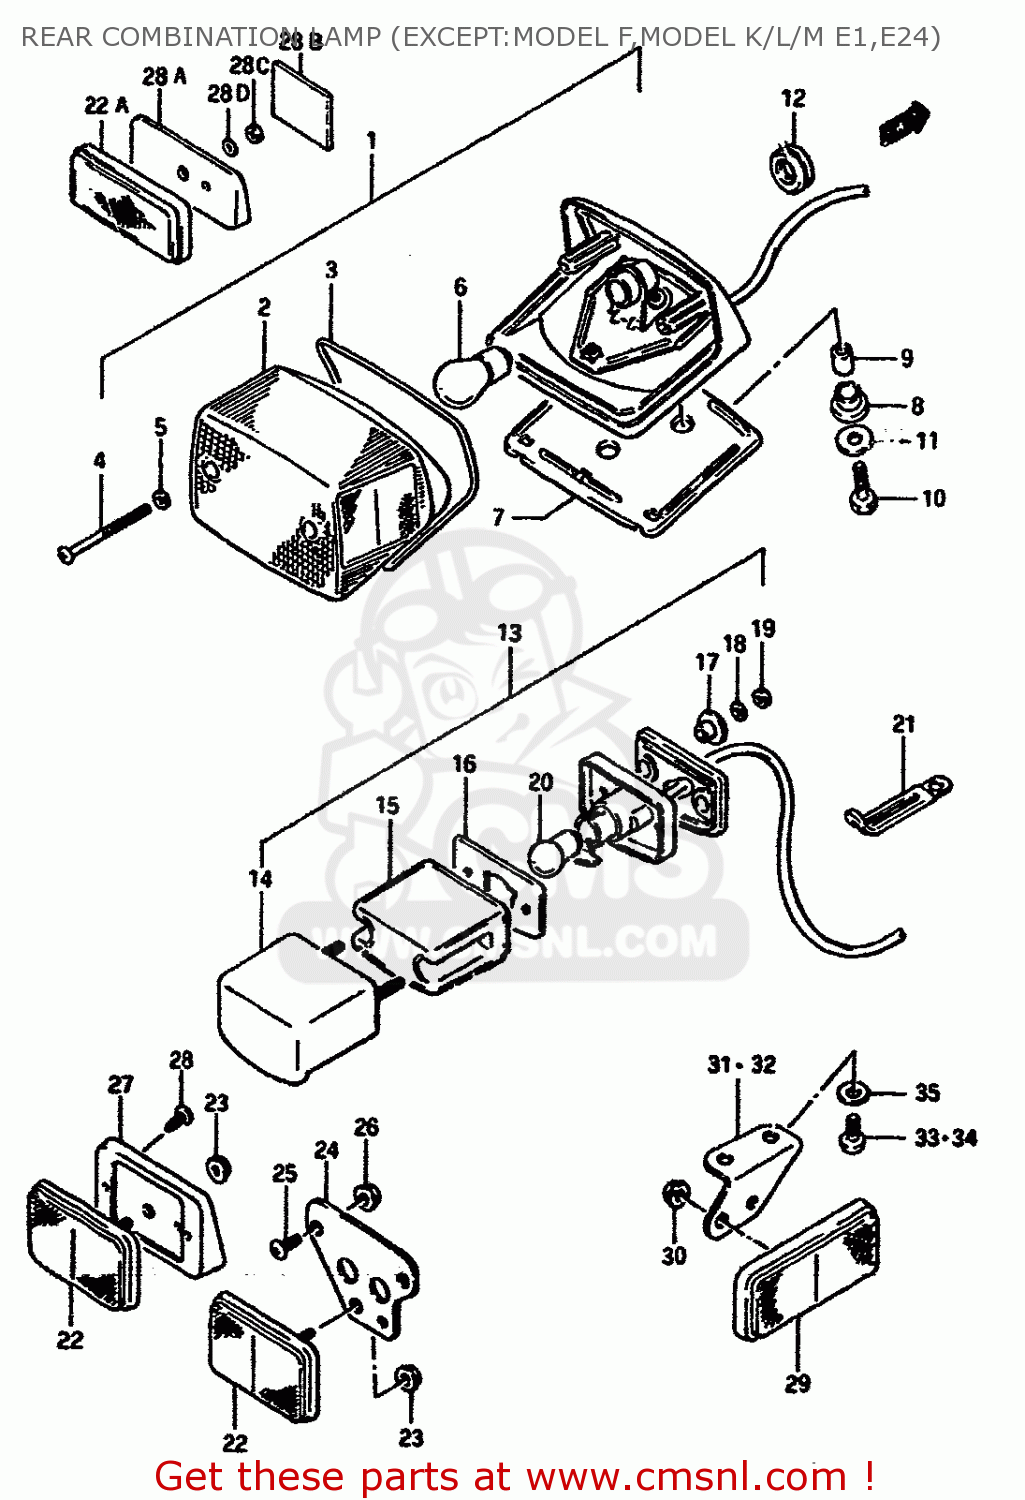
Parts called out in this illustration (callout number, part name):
1	LAMP ASSY,RR COMBINATION
2	LENS
3	GASKET (NAS)
4	SCREW
5	GASKET (NAS)
6	BULB(12V21/5W)
7	CUSHION
8	CUSHION
9	SPACER
10	BOLT
11	WASHER
12	GROMMET
13	LAMP ASSY,LICENSE
14	COVER,LICENSE LAMP
15	LENS
16	GASKET,LICENSE LAMP (NAS)
17	SPACER
18	WASHER,LOCK 4M
19	NUT
20	BULB
21	CLAMP L:35
22	REFLEX REFLECTOR ASSY,RR
22A	REFLEX REFLECTOR ASSY,RR
23	NUT
24	BRACKET
25	SCREW 5X10
26	NUT
27	SPACER
28	SCREW
28A	SPACER
28B	COVER,HARNESS
28C	NUT 5MM
28D	WASHER
29	REFLEX REFLECTOR,FR SIDE
30	NUT
31	BRACKET,RR SIDE RR,L
32	BRACKET,RR SIDE RR,R
33	SCREW
34	SCREW 6X12
35	WASHER (6.3X14X1.6)
